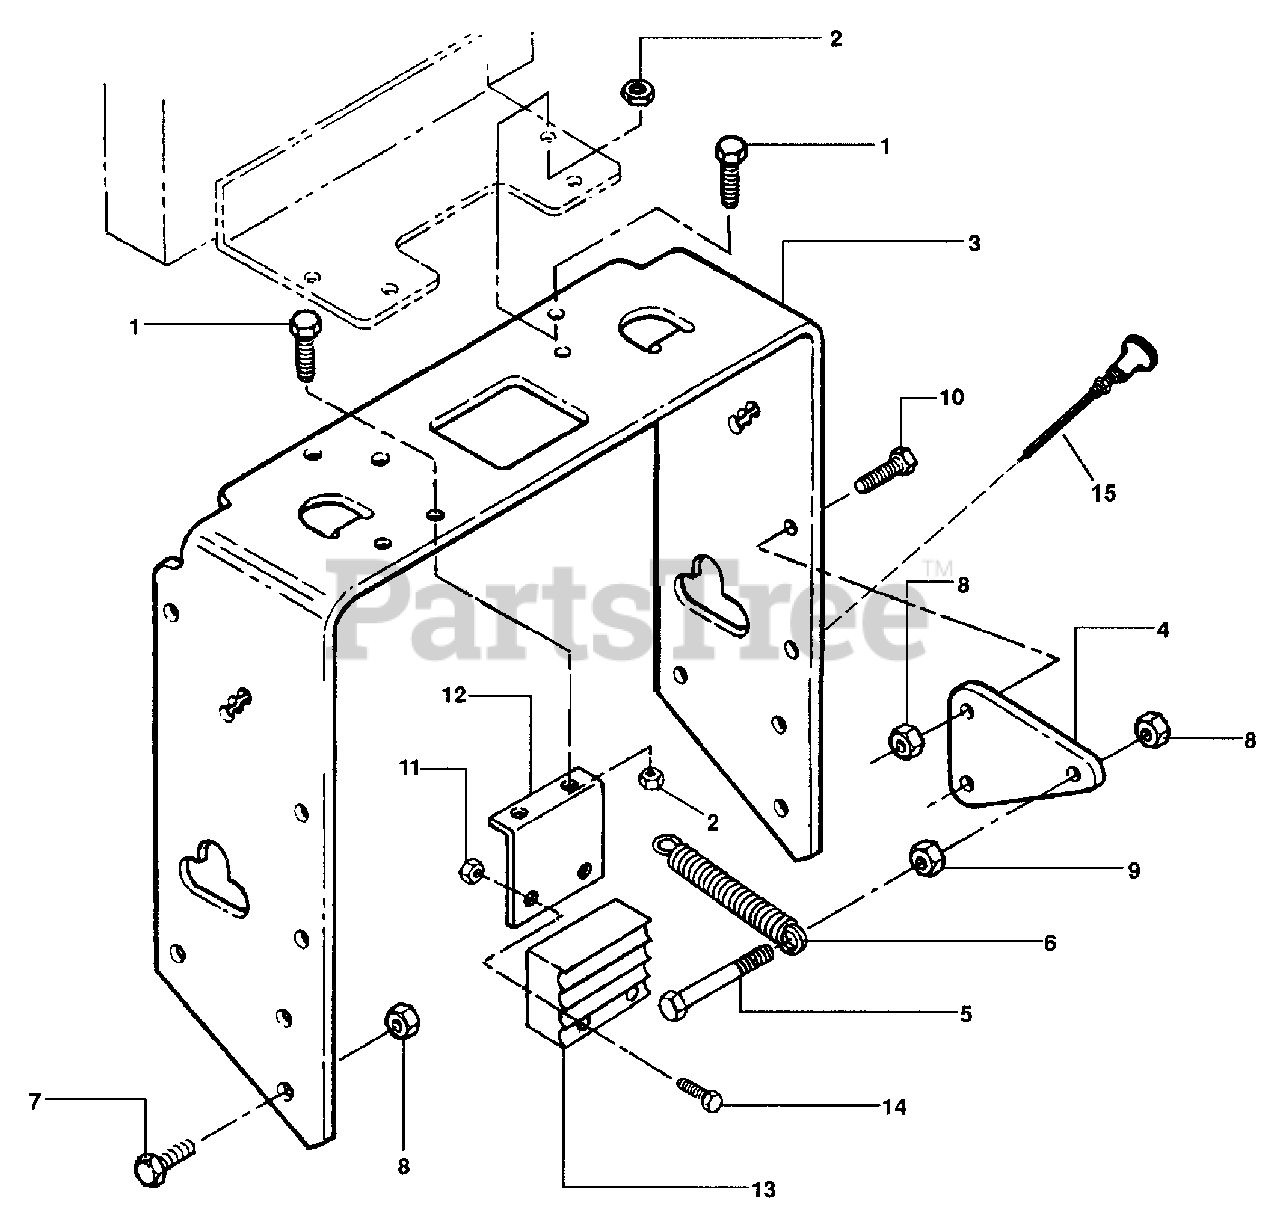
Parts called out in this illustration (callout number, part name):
1	SCREW, 5/16-18 X 1"
2	NUT, 5/16 Nyloc
3	TANK MOUNT BRACKET
4	SPRING MOUNT PLATE
5	BOLT, 3/8-16 X 2" Hex Head Cap
6	SPRING, Drive
7	BOLT, 3/8-16 X 1" Flanged
8	NUT, 3/8-16 Nyloc
9	NUT, 3/8-16
10	BOLT, 3/8-16 X 1"
11	NUT, 1/4-20 Nyloc
12	BRACKET, Module, Electric Clutch
13	MODULE, Electric Clutch
14	SCREW, 1/4-20 X 3/4"
15	CONTROL, Choke
